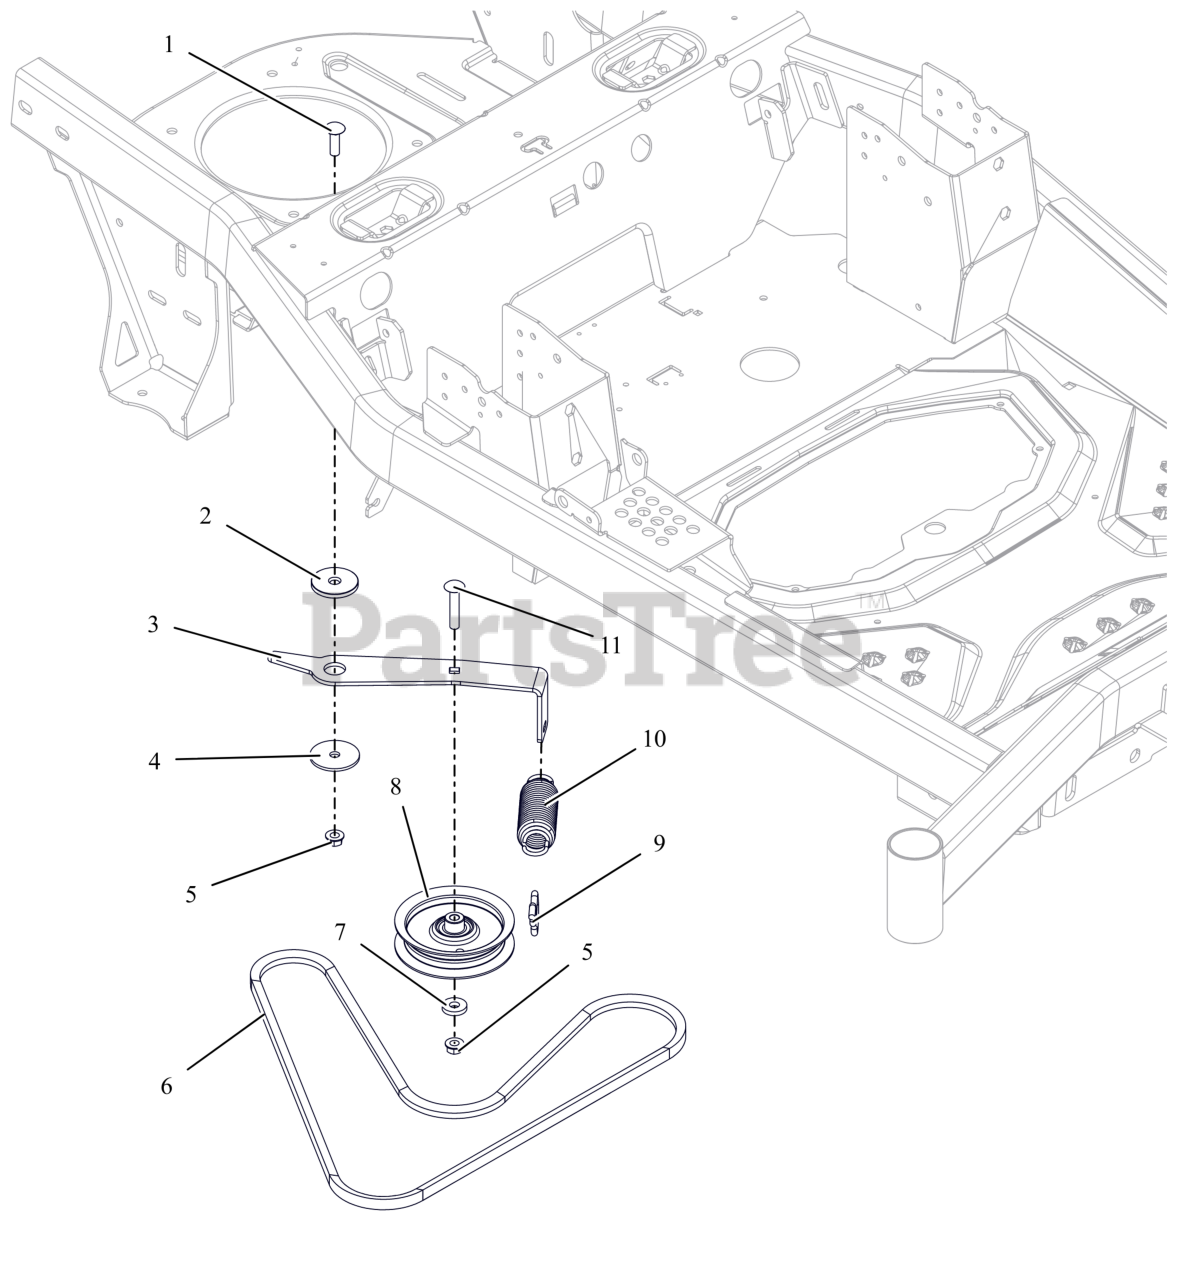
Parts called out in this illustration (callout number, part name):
1	BLT,RHSSN .38-16X1.25 G5 ZCC
2	BSHG-FLG .406X.88X.43X.25
3	ARM- GROUND DRIVE IDLER
4	WSHR-FL-STL 0.406X2X0.125 ZCC
5	NUT-LK-CTR-FLG .375-16 GF ZCC
6	V-BELT, A-RAW EDGE COGGED
7	WSHR, FLT .406X1.00X.188 ZCC
8	IDLER, FLAT - 4.06" X .75"
9	HOOK- WIRE FORMED SPRING
10	SPRG, EXTENSION
11	BLT,RHSSN.375-16X2.00 G5 ZCC
